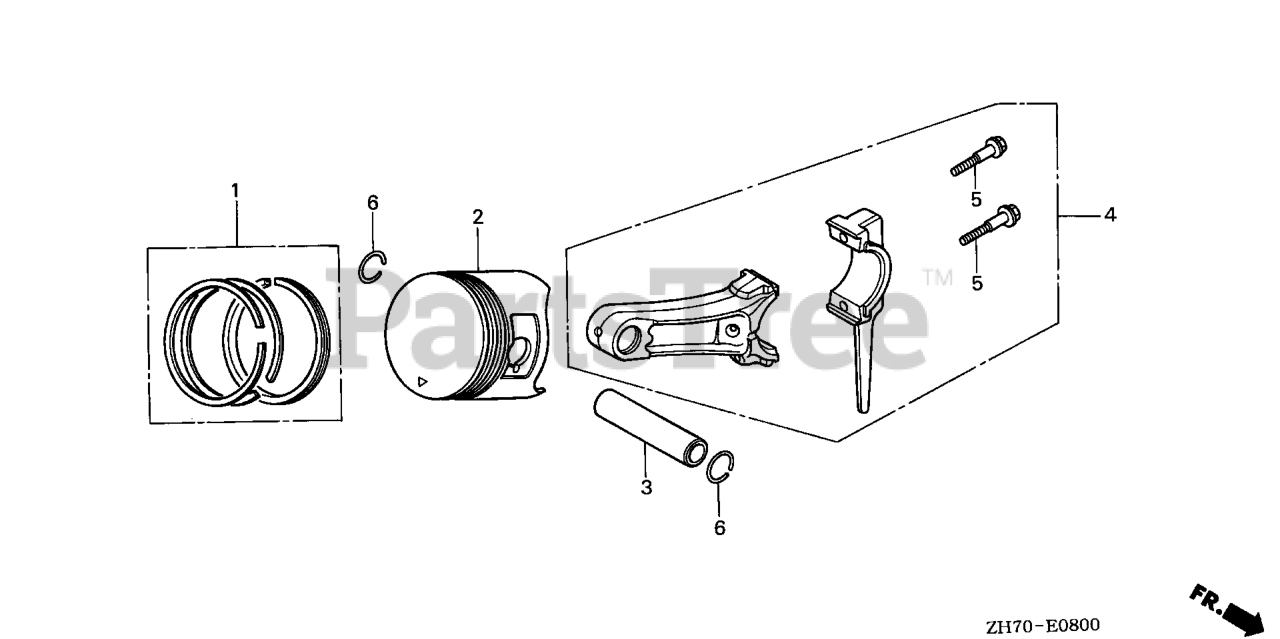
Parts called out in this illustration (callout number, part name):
1	RING SET, PISTON (STD) (NIPPON)
1	RING SET, PISTON (OVER SIZE) (0.25) (NIPPON) Use up to Engine SN 3993725.
1	RING SET, PISTON (OS 0.25) (Honda Code 7066418). (NIPPON)
1	RING SET, PISTON (OS 0.25) Use from Engine SN 3284617 to 3993725.
1	RING SET, PISTON (OVER SIZE) (0.50) (NIPPON) Use up to Engine SN 3993725.
1	RING SET, PISTON (0.50) (TEIKOKU)
1	RING SET, PISTON (OS 0.50) (Honda Code 7066426). (TEIKOKU)
1	RING SET, PISTON (OS 0.50) (Honda Code 7066434). (NIPPON)
1	RING SET, PISTON (OS 0.50) Use from Engine SN 3284617 to 3993725.
1	RING SET, PISTON (OVER SIZE) (0.75) (NIPPON) Use up to Engine SN 3993725.
1	RING SET, PISTON (0.75) Use up to Engine SN 3993725.
1	RING SET, PISTON (0.75) (Honda Code 7066459). (NIPPON)
1	RING SET, PISTON (0.75) (TEIKOKU)
1	RING SET, PISTON (0.75) Use from Engine SN 3284617 to 3993725.
2	PISTON (STD)
2	PISTON (OS 0.25) Use up to Engine SN 3993725.
2	PISTON (OVER SIZE) (0.50) Use up to Engine SN 3993725.
2	PISTON (OVER SIZE) (0.50) Use from Engine SN 3993726.
2	PISTON (0.75)
2	PISTON (0.75) Use up to Engine SN 3993725.
3	PIN, PISTON
4	ROD ASSY., CONNECTING (UNDER SIZE)
4	ROD ASSY., CONNECTING
4	CONN ROD ASSY.
5	BOLT, CONNECTING ROD
6	CLIP, PISTON PIN (13MM)
